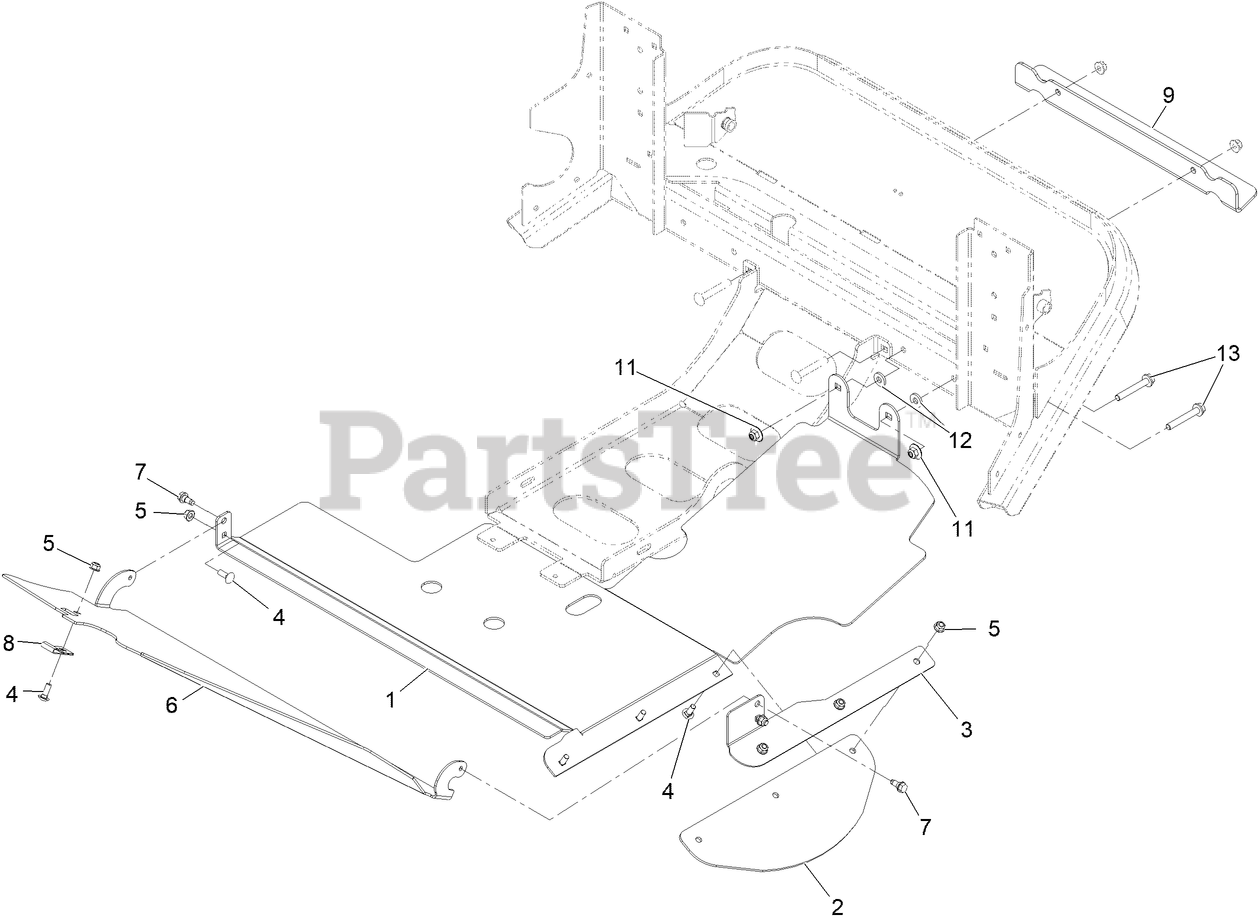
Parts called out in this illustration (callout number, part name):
1	PLATE-DISCHARGE
2	FLAP-RUBBER
3	BRACKET-FLAP, LH
4	SCREW-CARR
5	NUT-HF, NI
6	PANEL-DISCHARGE
7	SCREW-SHOULDER
8	BEARING-STRAP, NYLON
9	BRACKET-TIE DOWN
11	NUT-FLANGE, NI
12	SPACER
13	SCREW-HHF
